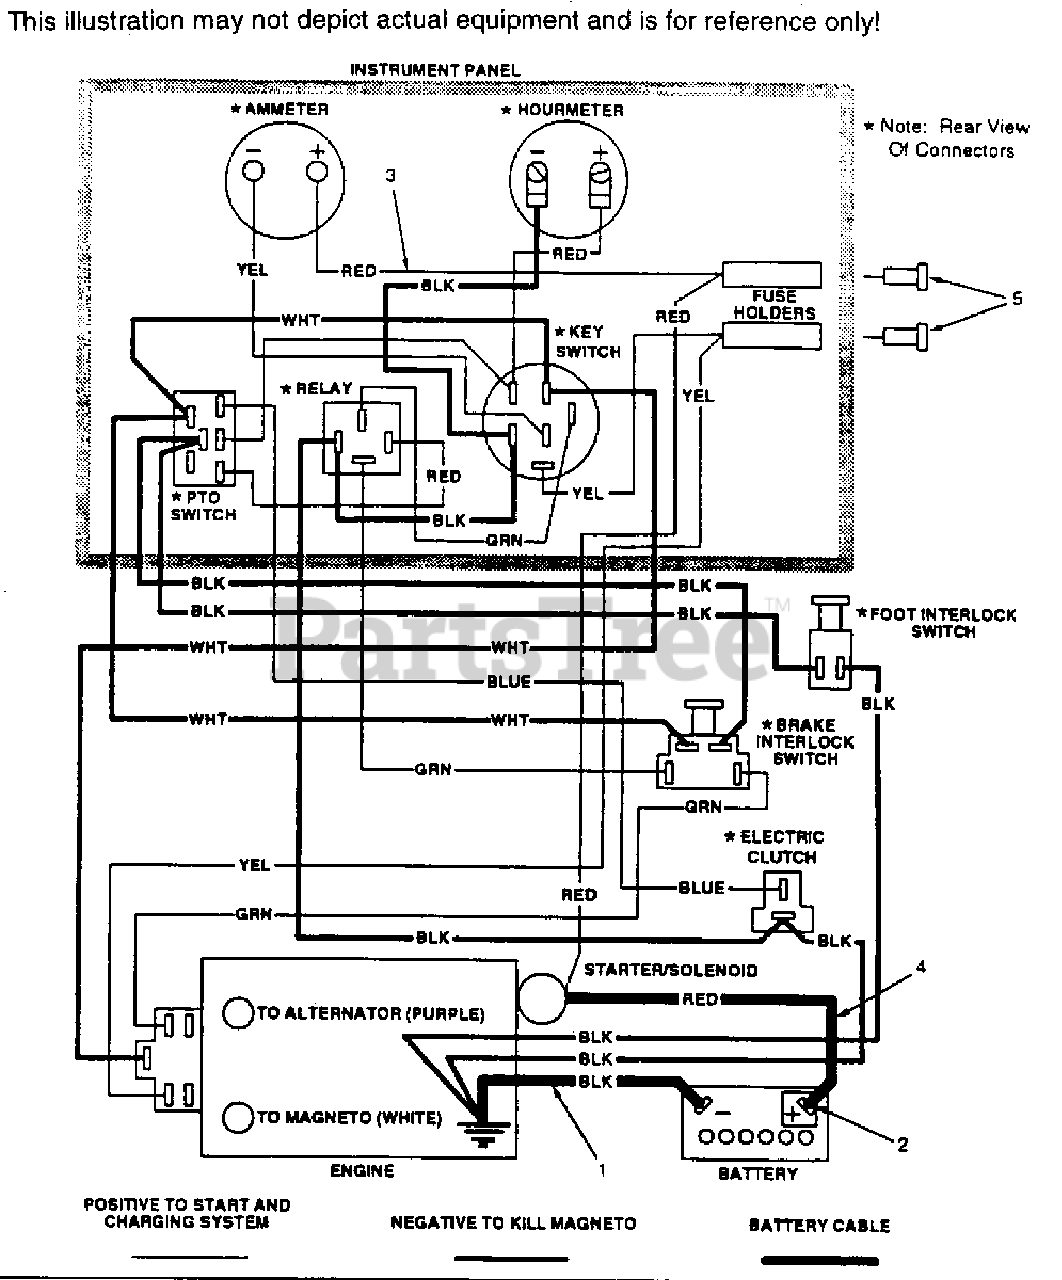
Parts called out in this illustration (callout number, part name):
1	BATTERY CABLE 27" BLACK
2	RUBBER BOOT
3	WIRE HARNESS STHM
4	BATTERY CABLE 18" RED
5	FUSE, 20 AMP BLADE AUTOMOTIVE
